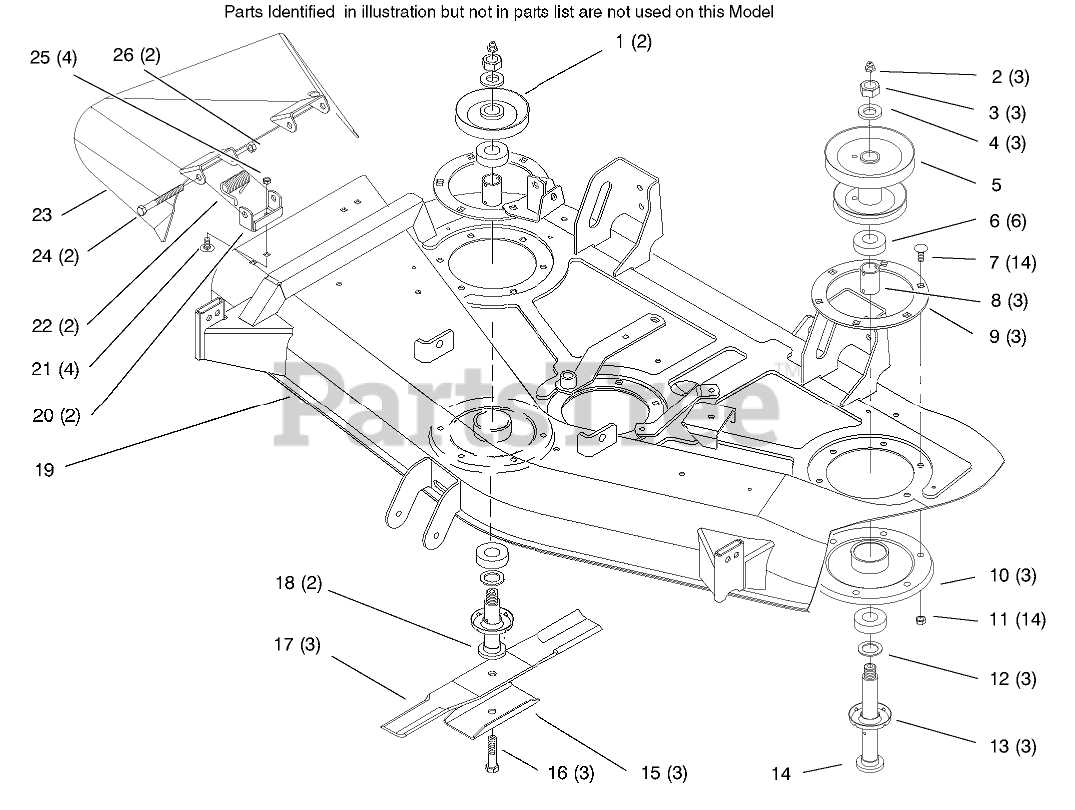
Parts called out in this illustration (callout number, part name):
1	PULLEY
2	FITTING-GREASE
3	NUT-JAM
4	WASHER-FLAT
5	PULLEY-DOUBLE
6	BEARING-BALL
7	SCREW-CARR
8	SPACER-BEARING
9	RING-DECK SUPPORT
10	HOUSING-SPINDLE
11	NUT-HF
12	WASHER-BACKUP
13	SHIELD-BEARING
14	SHAFT - SPINDLE
15	STIFFENER-BLADE
16	SCREW-BLADE
17	Blade
18	SHAFT-SPINDLE
19	DECK ASM
20	BRACKET-PIVOT
21	SCREW-CARR
22	SPRING
23	ASSEMBLY-DEFLECTOR DECAL
24	SCREW-HH
25	NUT-LOCK, NI
26	NUT-HEX
